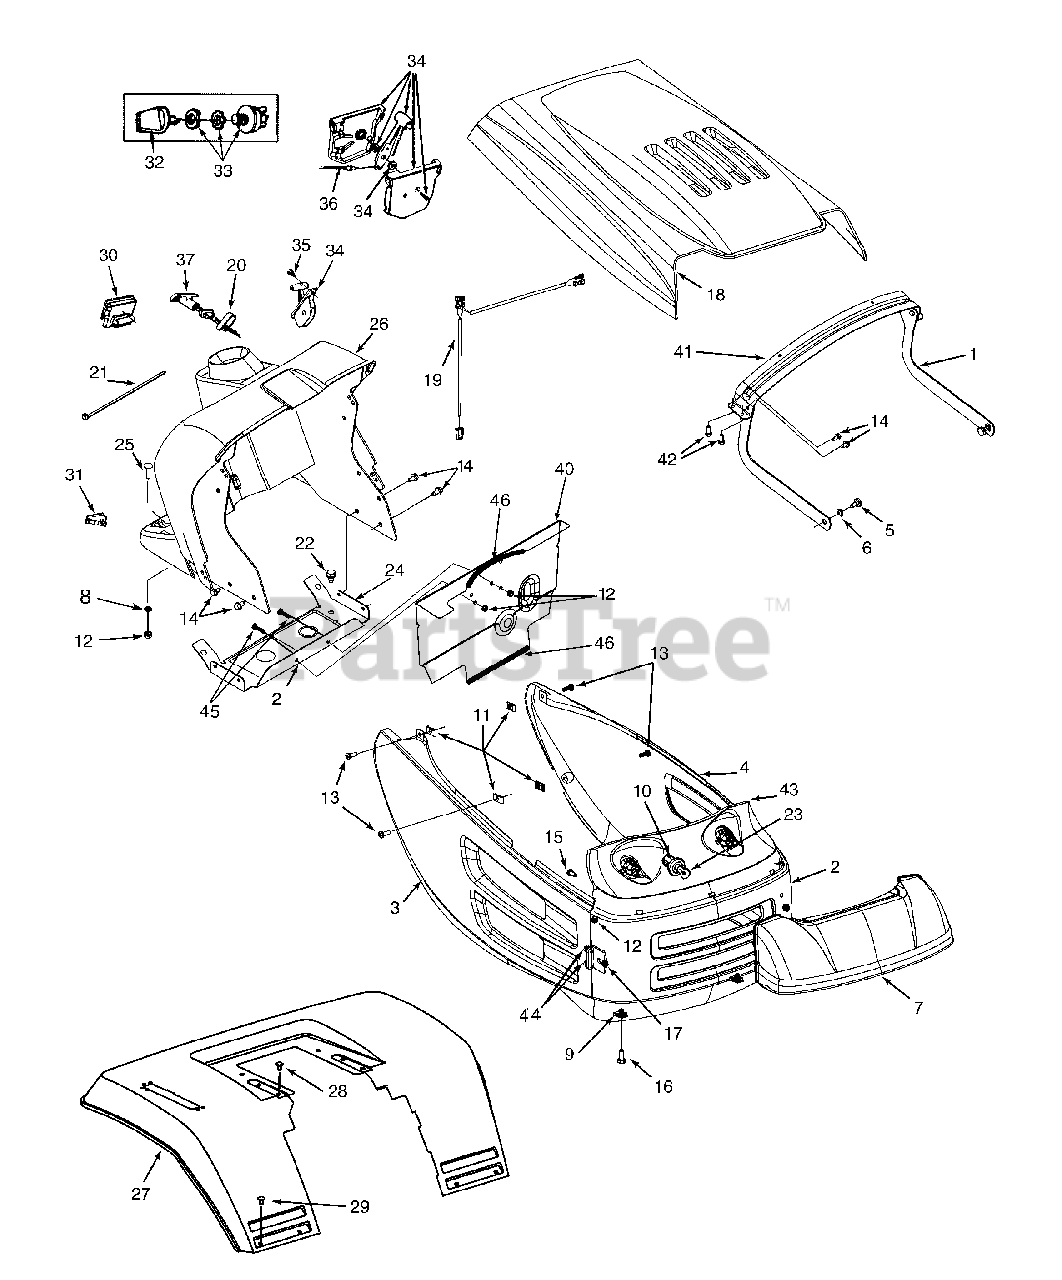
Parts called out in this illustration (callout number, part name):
6	Spr. Wash. .39" I.D. x .62" O.D.
7	Lens
8	Retainer Nut
9	U - Nut 5/16-18 Thd
10	Socket
11	Tinn. Nut 1/4-20 Thd.
12	Hex Sems Nut 1/4-20 Thd.
13	Pan Hd. Mach. Scr. 1/4-20 x .75" Lg.
14	Hex Wash. Hd. TT-Tap Scr. 1/4-20 x .5"
15	Hex Bolt
16	Hex Bolt 5/16-18 x .1" Lg. (Gr.5)
19	Headlight Harness
20	Choke Retainer
21	Cable Tie
22	Hex Wash. Hd. Tap Scr. 5/16-18 x .5"
23	Lamp
26	Dash Panel
29	Truss Mach. Scr. 1/4-20 x .5" Lg.
30	Ammeter
31	Light Switch
32	Ignition Key
33	Ignition Switch
34	Throttle Box Assembly
35	Truss Mach. AB-Tap Scr. #10 x .5"
36	Throttle Control Wire 18.5" Lg.
37	Choke Control 20" Lg.
43	Retainer Nut
44	Hex Wash. AB-Tap Scr. 1/4-14 x .625"
45	Pan Hd. Scr. 1/4-20 x 1" Lg.
46	Trim Strip
